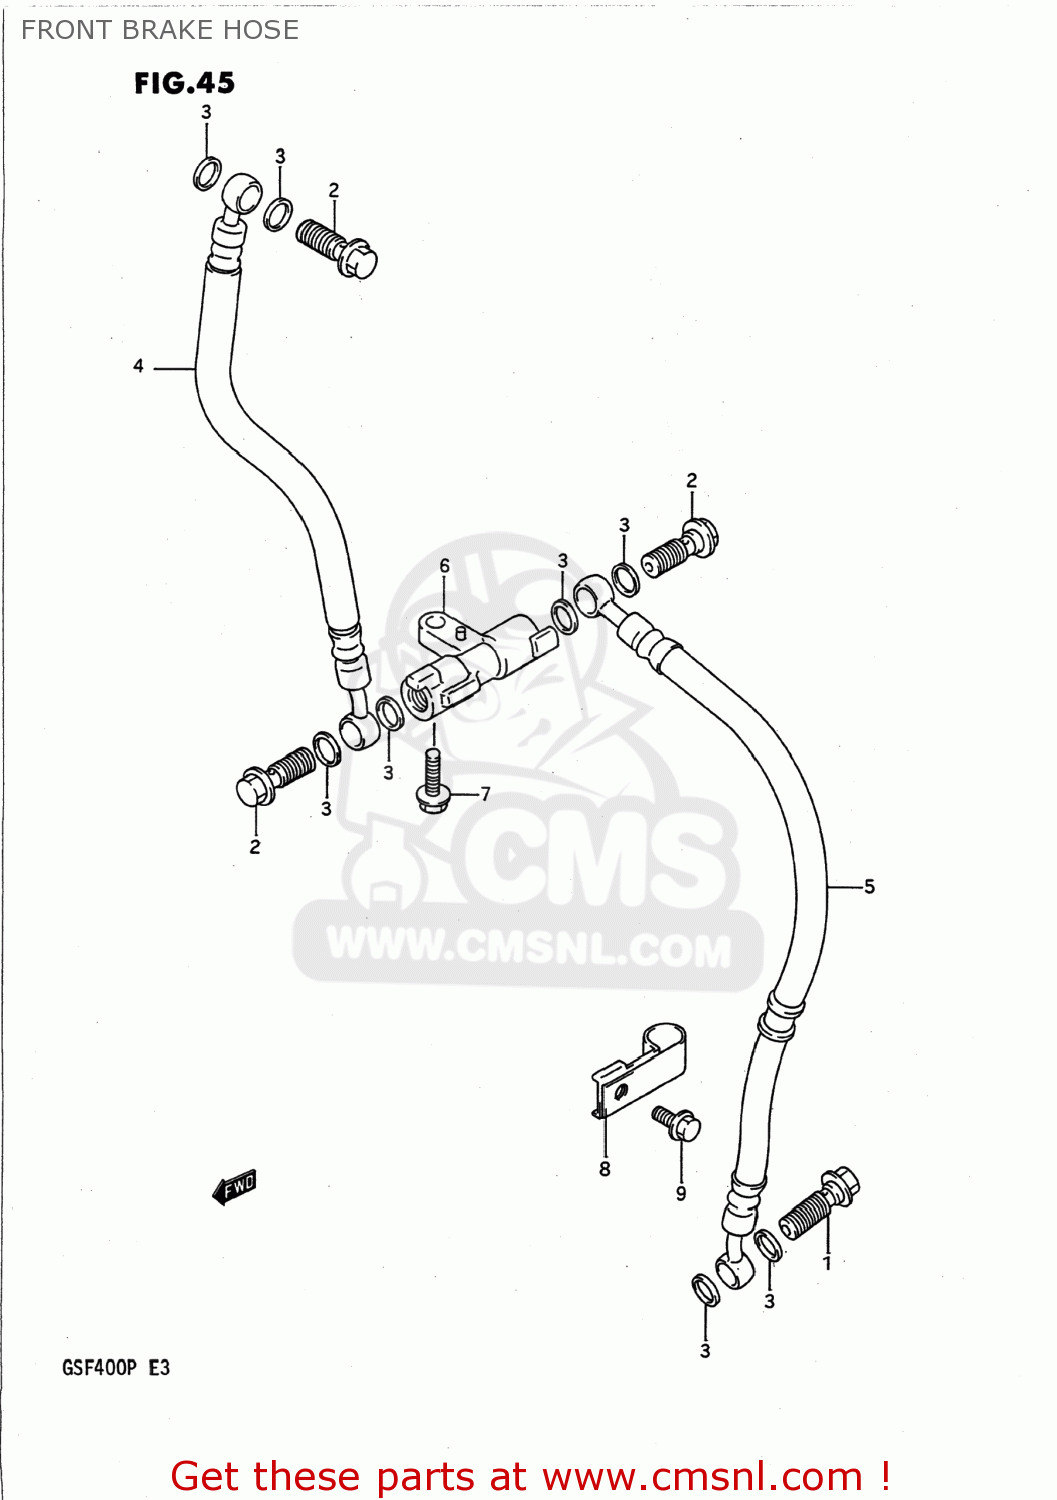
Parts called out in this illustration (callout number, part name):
1	BOLT 10X1.25X24
2	BOLT UNION
3	WASHER(10X15X1.5)
4	HOSE,FR BRAKE
5	HOSE COMP,FRONT BRAKE
6	JOINT,BRAKE HOSE
7	BOLT 6X16
8	CLAMP,FRONT BRAKE NO.2
9	BOLT 6X12
